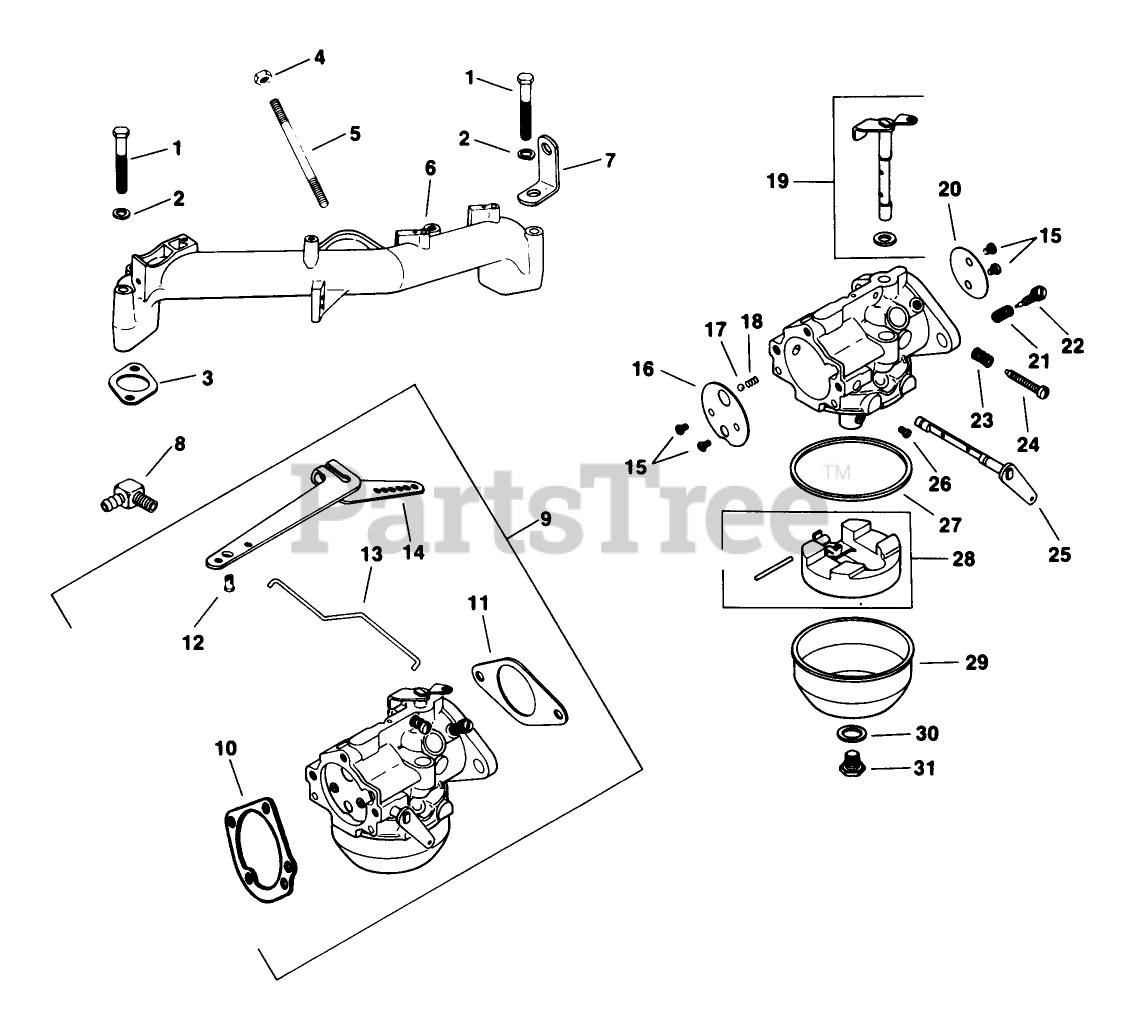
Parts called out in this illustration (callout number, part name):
1	Screw-H.C.
2	Washer
3	Gasket-Intake
6	Manifold-Intake
7	Strap-Lifting
8	Connector-90?
9	Kit-Carburetor w/Linkage (Incl. Ref. #10-31)
10	Gasket
11	Gasket
12	Bushing-Linkage (Yellow)
13	Linkage-Governor
14	Arm-Governor
15	Screw-Throttle Plate
16	Plate-Choke
17	Ball-Choke
18	Spring-Choke
19	Shaft Assembly
20	Plate-Throttle
22	Valve-Needle
25	Lever-Choke
26	Jet-Main
27	Bowl-Gasket
28	Kit-Float
30	Gasket-Bowl
31	Screw-Bowl
